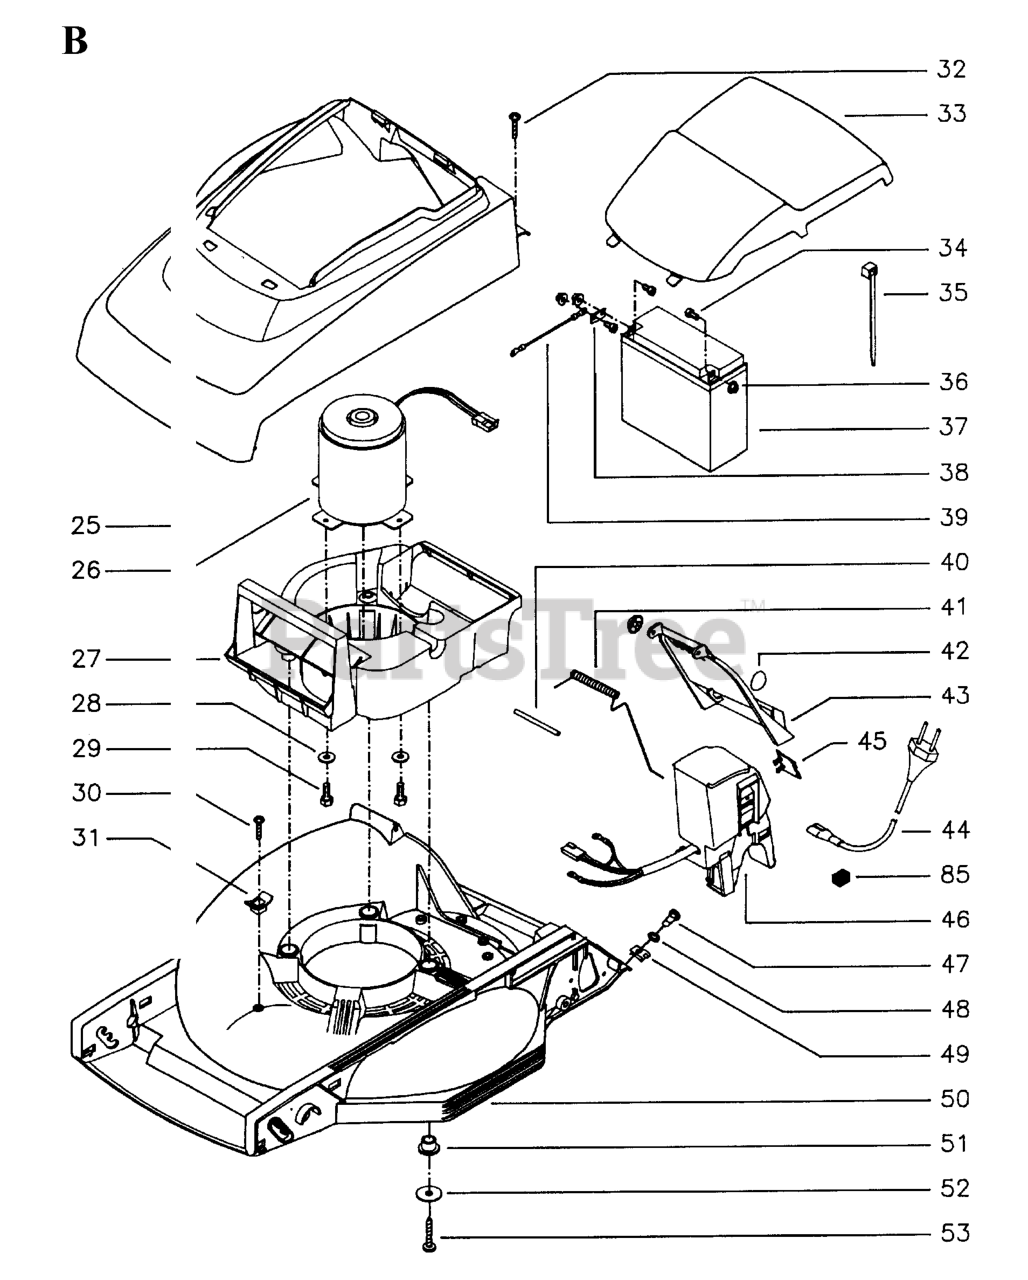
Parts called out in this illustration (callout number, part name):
32	SCREW
40	PIN
49	LOCK PLATE
